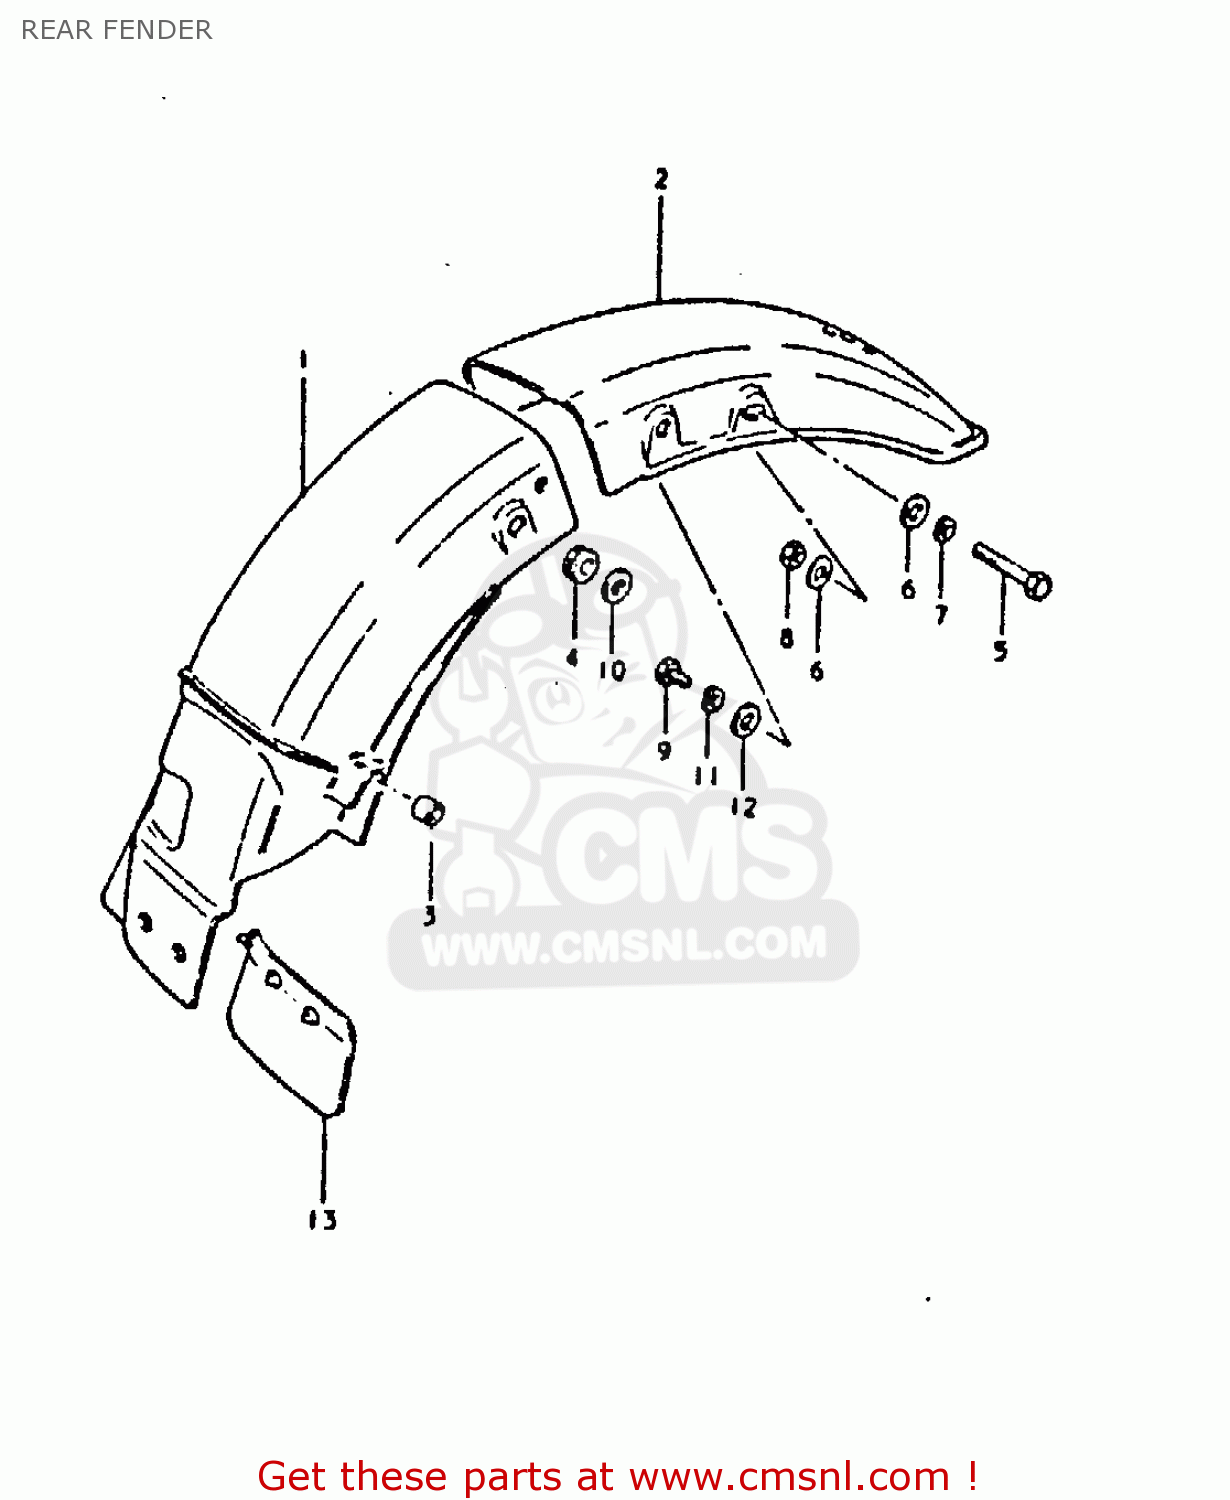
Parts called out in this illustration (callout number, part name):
1	BODY,REAR FENDER,FRONT
2	BODY, REAR FENDER REAR
3	CUSHION
4	CUSHION
5	BOLT
6	WASHER
7	LOCK WASHER
8	NUT
9	BOLT 8X12
10	WASHER
11	LOCK WASHER
12	WASHER
13	GUIDE,RR FENDER MUD
